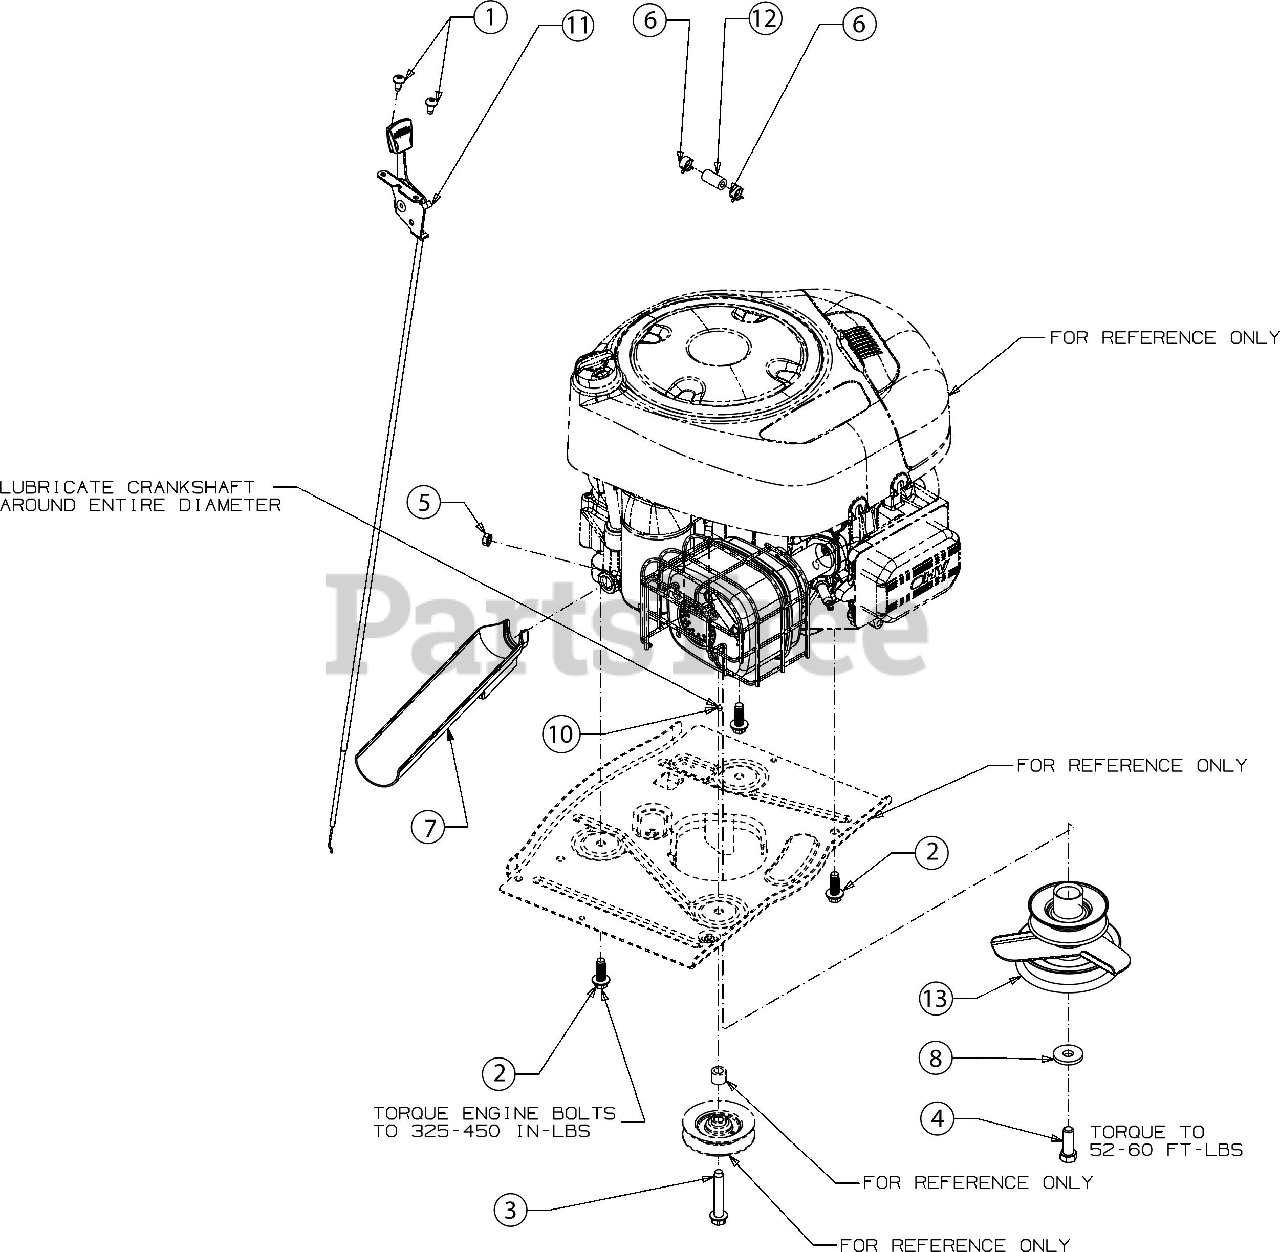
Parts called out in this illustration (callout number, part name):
1	SCREW 1/4-20 x .500
2	SCREW 3/8-16 x 1
3	SCREW 3/8-16 x 2.250
4	SCREW 7/16-20 x 1.250 GR5
5	SEMS NUT 1/4-20
6	HOSE CLAMP 1/20
7	OIL DRAIN
8	FLAT WASHER .445 x 1.248 x .170
11	THROTTLE CABLE 31" x 1.1
12	FUEL HOSE LOW PERMEATION
13	ENGINE PULLEY
